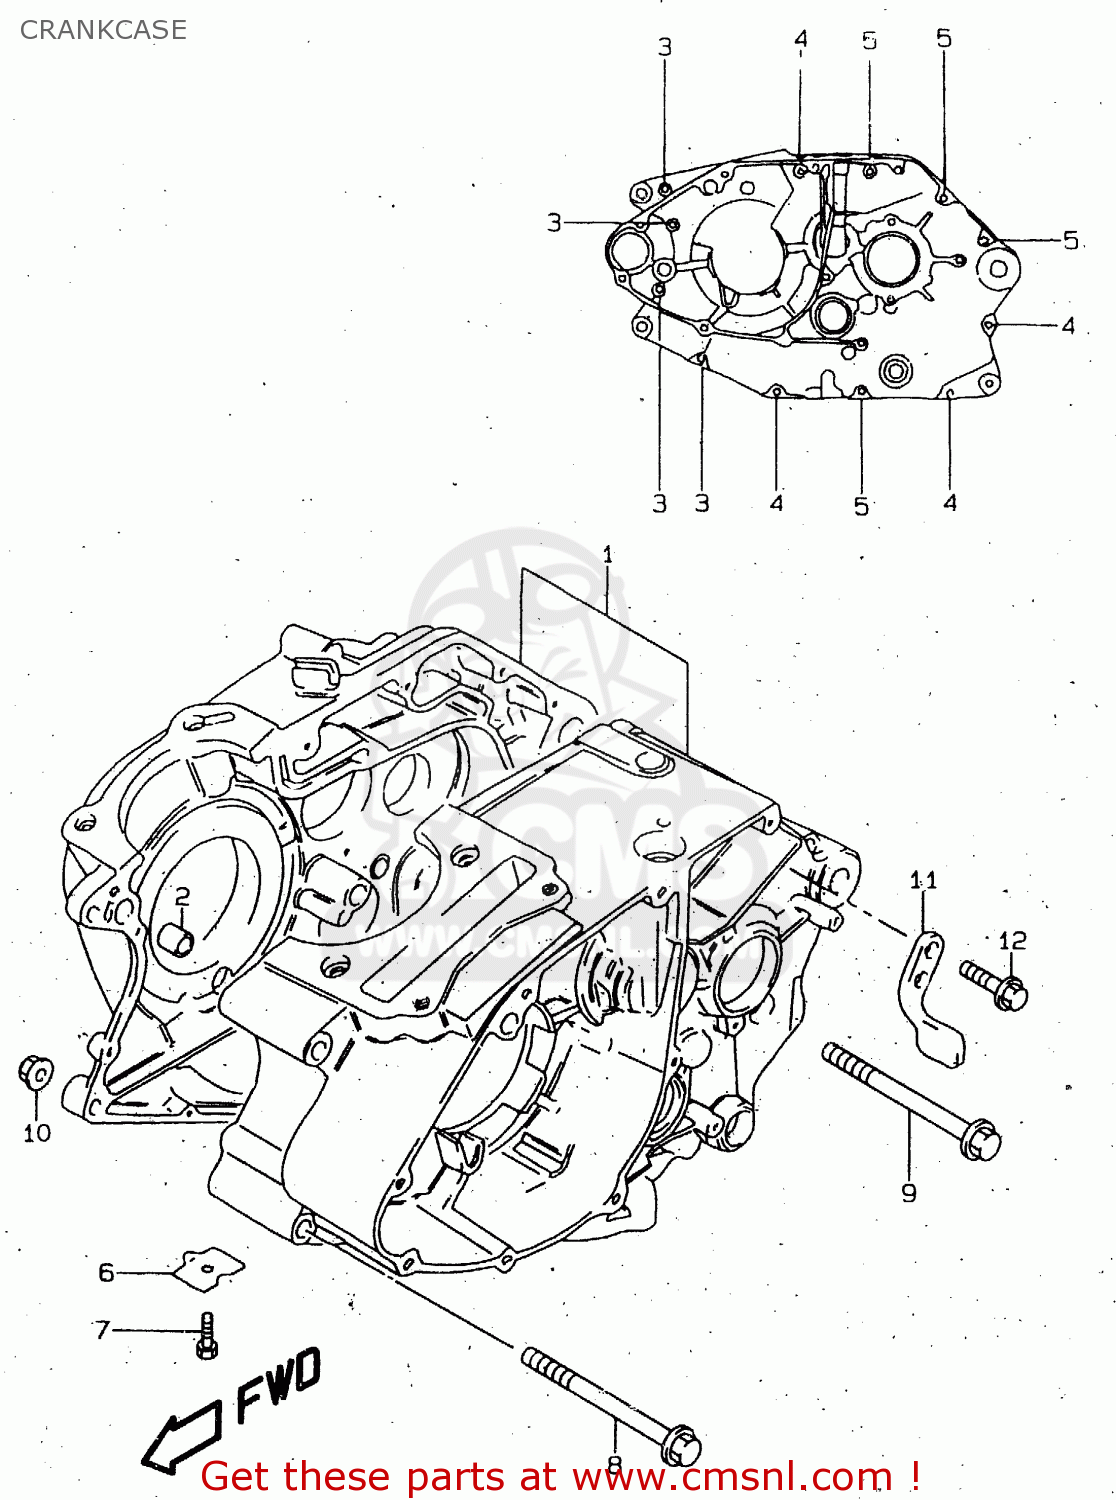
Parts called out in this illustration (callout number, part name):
1	CRANKCASE SET
2	PIN
3	BOLT
4	BOLT
5	BOLT
6	PLATE,OIL GALLERY PLUG
7	BOLT
8	BOLT(8X80)
9	BOLT(8X88)
10	NUT
11	LIMITER,ENGINE SPROCKET
12	SCREW(6X18)
